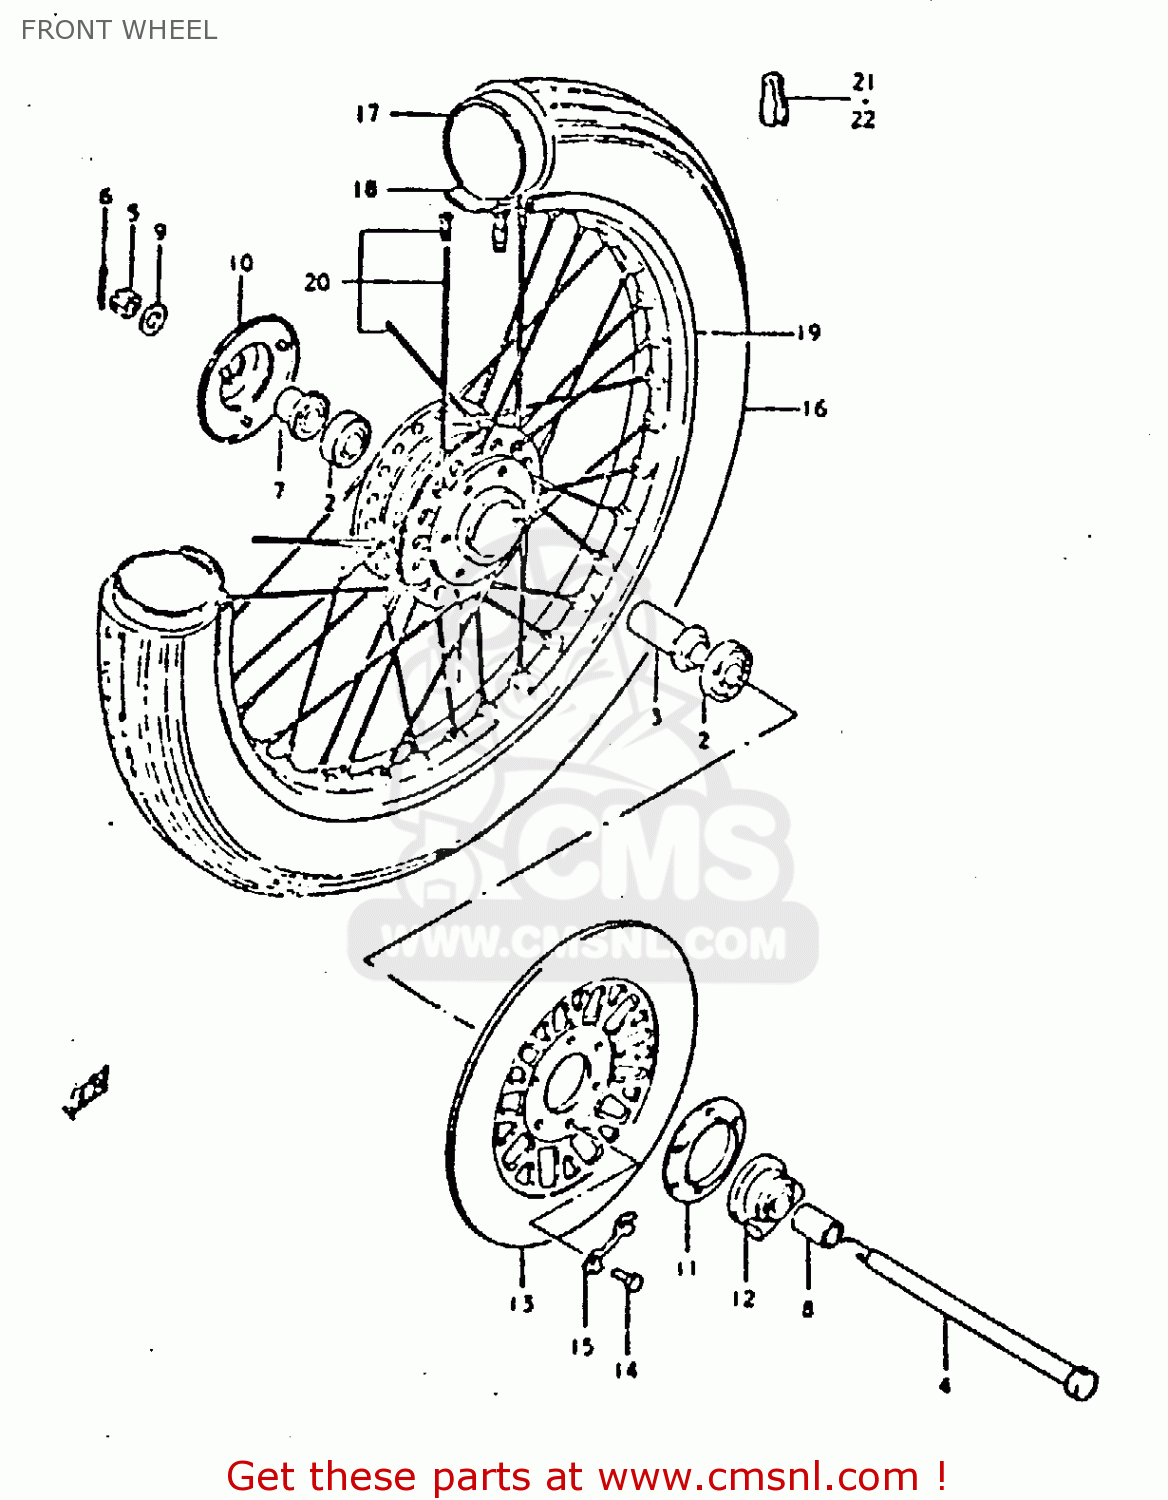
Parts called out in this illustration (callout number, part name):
1	DRUM,FRONT HUB
2	BEARING
3	SPACER,FR HUB BEARING
4	AXLE,FRONT
5	NUT 12MM
6	COTTER PIN
7	SPACER,FR HUB BEARING,R
8	SPACER(15X22X30)
9	WASHER
10	COVER,FR HUB,R
11	DUST SEAL,SPEEDOMETER GEAR BOX
12	BOX ASSY,SPEEDOMETER GEAR
13	DISC,FR BRAKE
14	BOLT(8X25)
15	WASHER
16	TIRE,FRONT
17	TUBE,INNER
18	PROTECTOR,INNER TUBE
19	RIM,FR WHEEL
20	SPOKE SET,FRONT
21	BALANCER,WHEEL (B)
22	BALANCER,WHEEL (30G)
